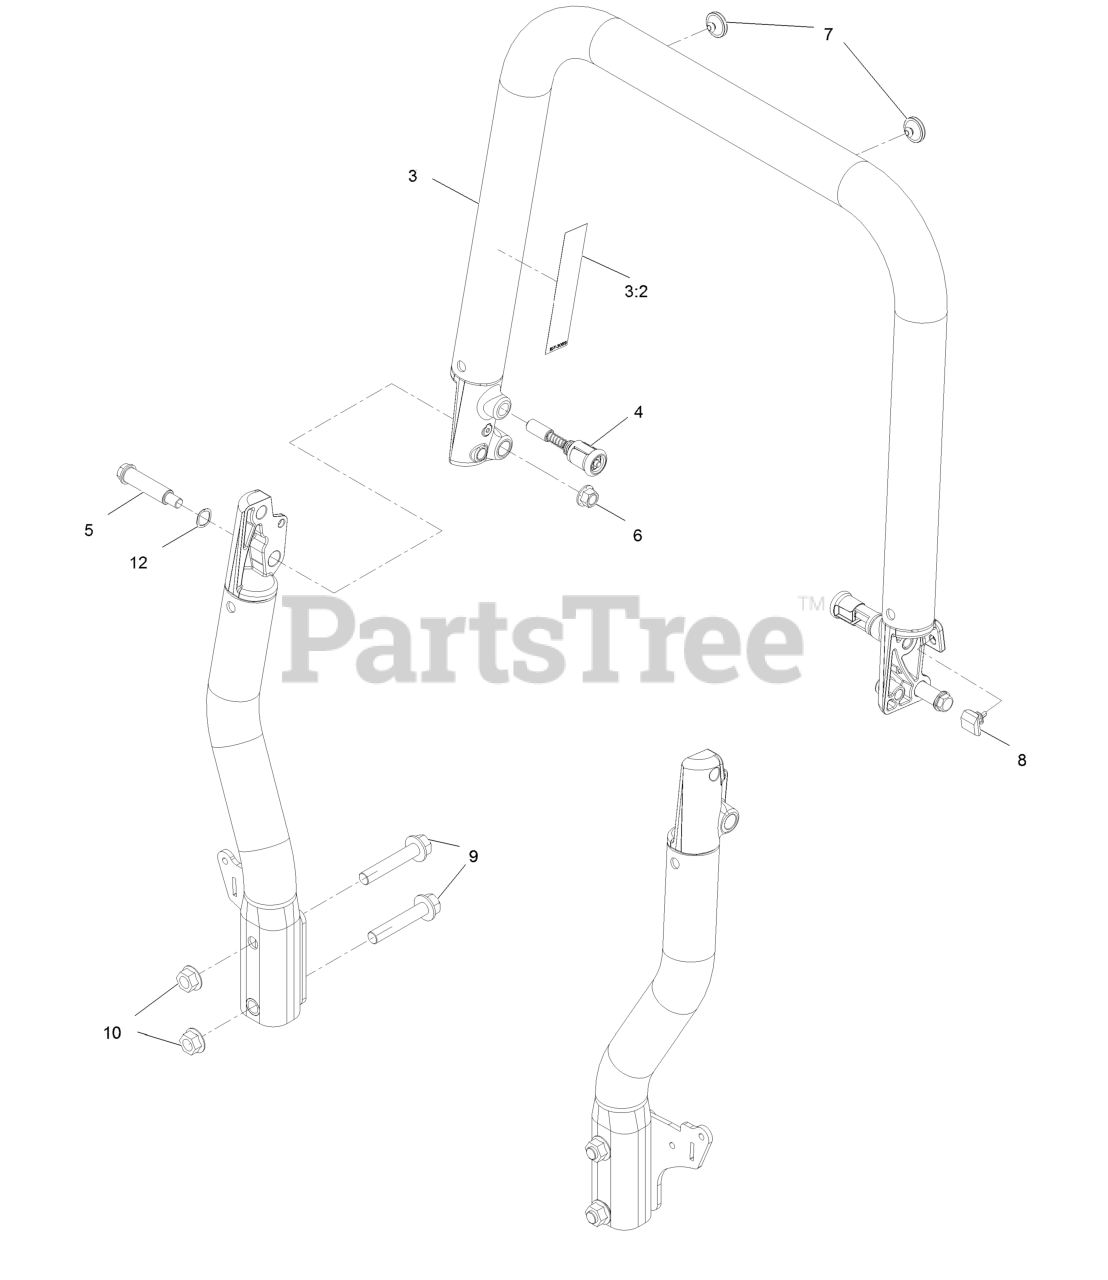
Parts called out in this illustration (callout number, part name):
3	Top Tube ASM
3:2	Decal-Warning
4	Pin-Spring
5	Bolt-Shoulder
6	Nut-Lock
7	Bumper, ROPS
8	Bumper-ROPS
9	Screw-HHF
10	Nut-Flange
12	Washer-Wave
